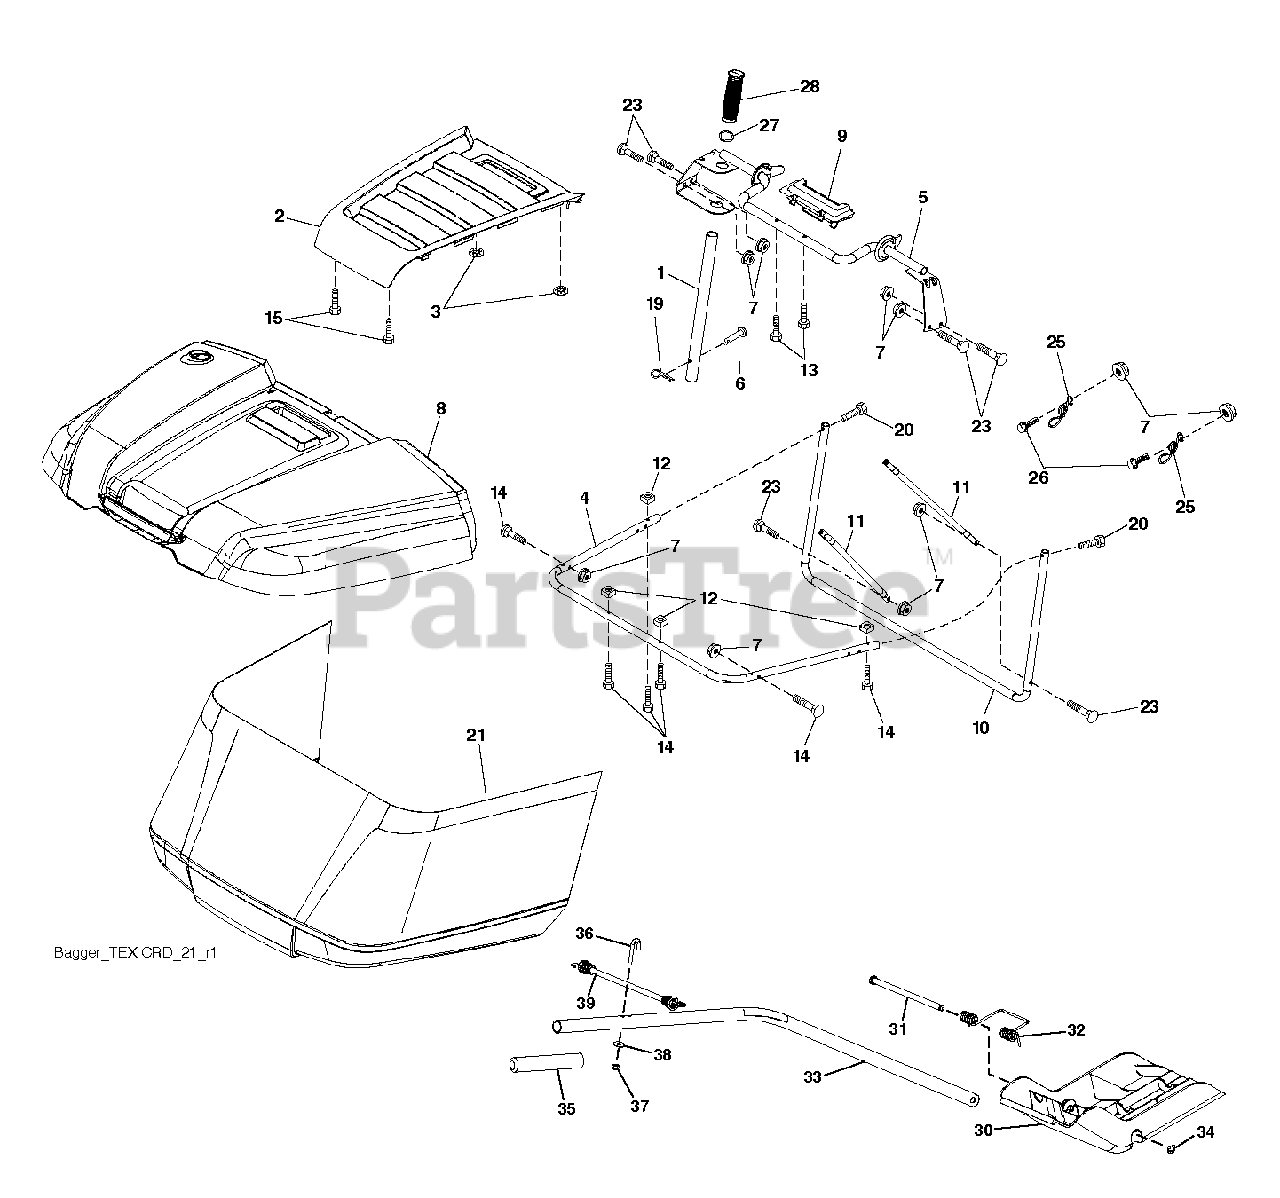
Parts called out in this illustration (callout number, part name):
1	TUBE.HANDLE.BAGGER.CRD/SRD.BLA
2	APPLIQUE.TOP.BAG.SRD.ORANGE
3	NUT.PUSH.156
4	SUBASM.TOP.TUBE.TEX.CRD
5	FRAME.ASM.TOP.BAGGER.SRD
6	RIVET,DRILLED
7	NUT T
8	BAGGER.TOP.SRD.APPLIQUE
9	INSERT.HANDLE.BAGGER.(2 2)
10	FRAME FRAME.FRONT.TEX.CRD
11	BRACE BRACE SIDE TUBE
12	NUT.SQUARE.1/4
13	SCREW.1/4X1.150.HXWSH
14	BOLT.SHOULDER.HX.WSH.1/4X1.150
15	SCREW,#8.FLAT.HEAD.DRILL.TIP
19	PIN.COTTER.5/16.BOW TI
20	SCREW.HEXCAP.1/4-20X1.375(2 2)
21	BAG SUBASM. TEX CRD GEN 2 HUSQ
25	SPRING.LATCH.BAGGER.SRD
26	SCREW HEX CRT
27	RB GROMMET.RUBBER.SRD
28	GRIP.HANDLE.BLACK
30	PLUG PLUG
31	PIN PIN.HINGE
32	SPRING SPRING DOUBLE TORSION
33	SHAFT SHAFT TEX CRD MULCH PLU
34	E-RING.5/16"
35	GRIP GRIP MULCH PLUG HAND
36	BOLT BOLT J
39	BUBGEE BUBGEE TEX CRD
